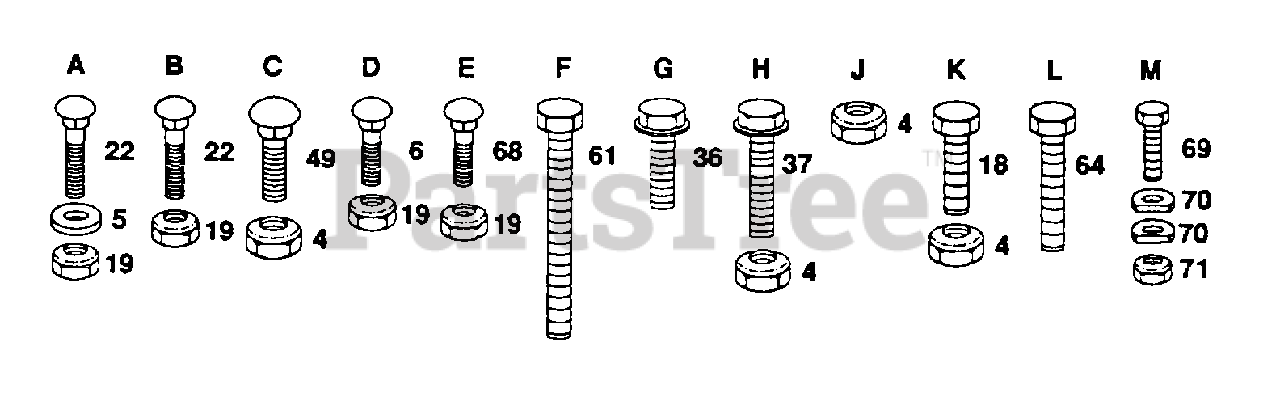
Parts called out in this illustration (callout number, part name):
5	WASHER M
6	BOLT
22	BOLT
36	SCREW
37	SCREW
49	BOLT
61	BOLT
64	BOLT.3/8-14X1.25
69	BOLT LT
70	WASHER T
